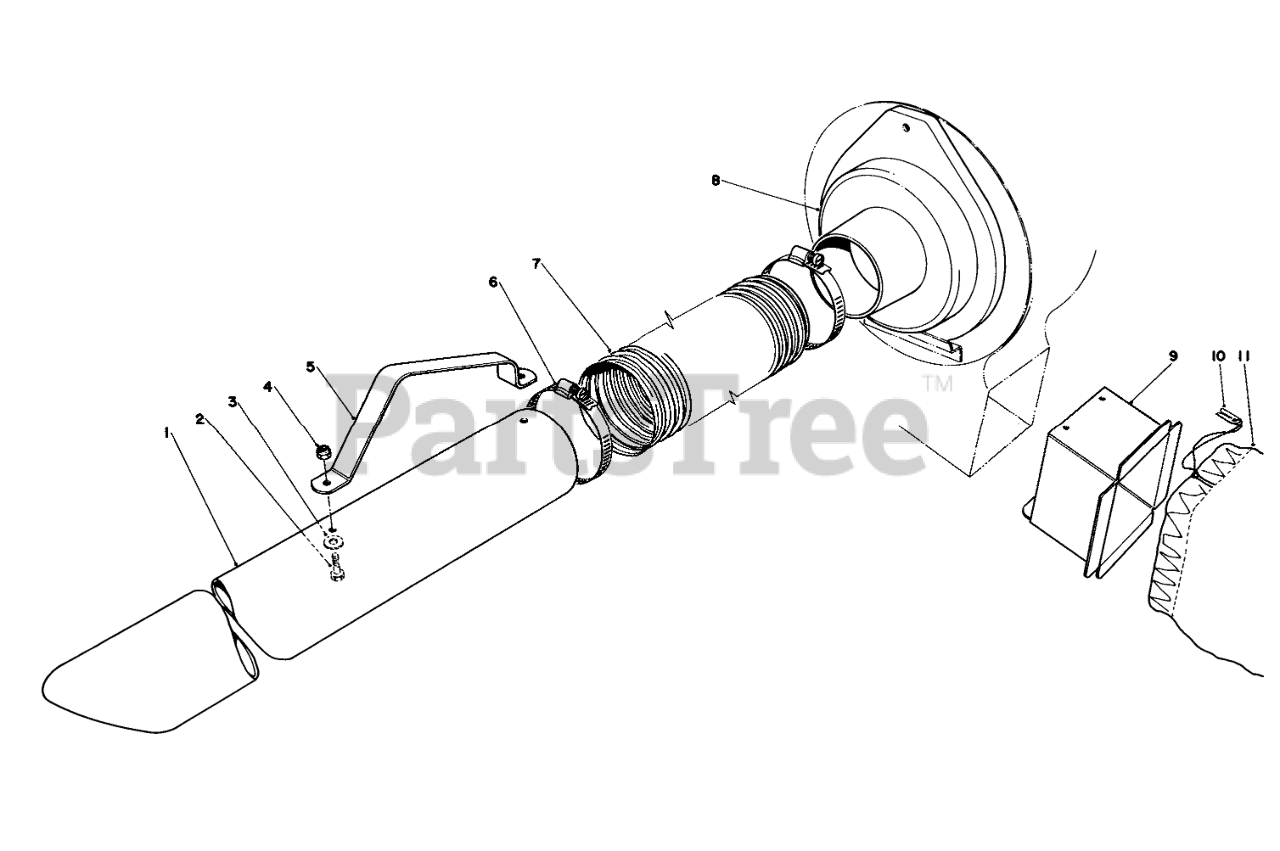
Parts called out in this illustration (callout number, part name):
1	NOZZLE
2	SCREW-HH
3	SPECIAL WASHER
4	NUT-KEPS
5	NOZZLE HANDLE
6	CLAMP
7	VACUUM HOSE
8	ADAPTOR HOSE TO HSG
9	HOUSING WA BLOWER BAG
10	BAG CORD FASTENER
11	GIANT BAG(29-9860) WW
